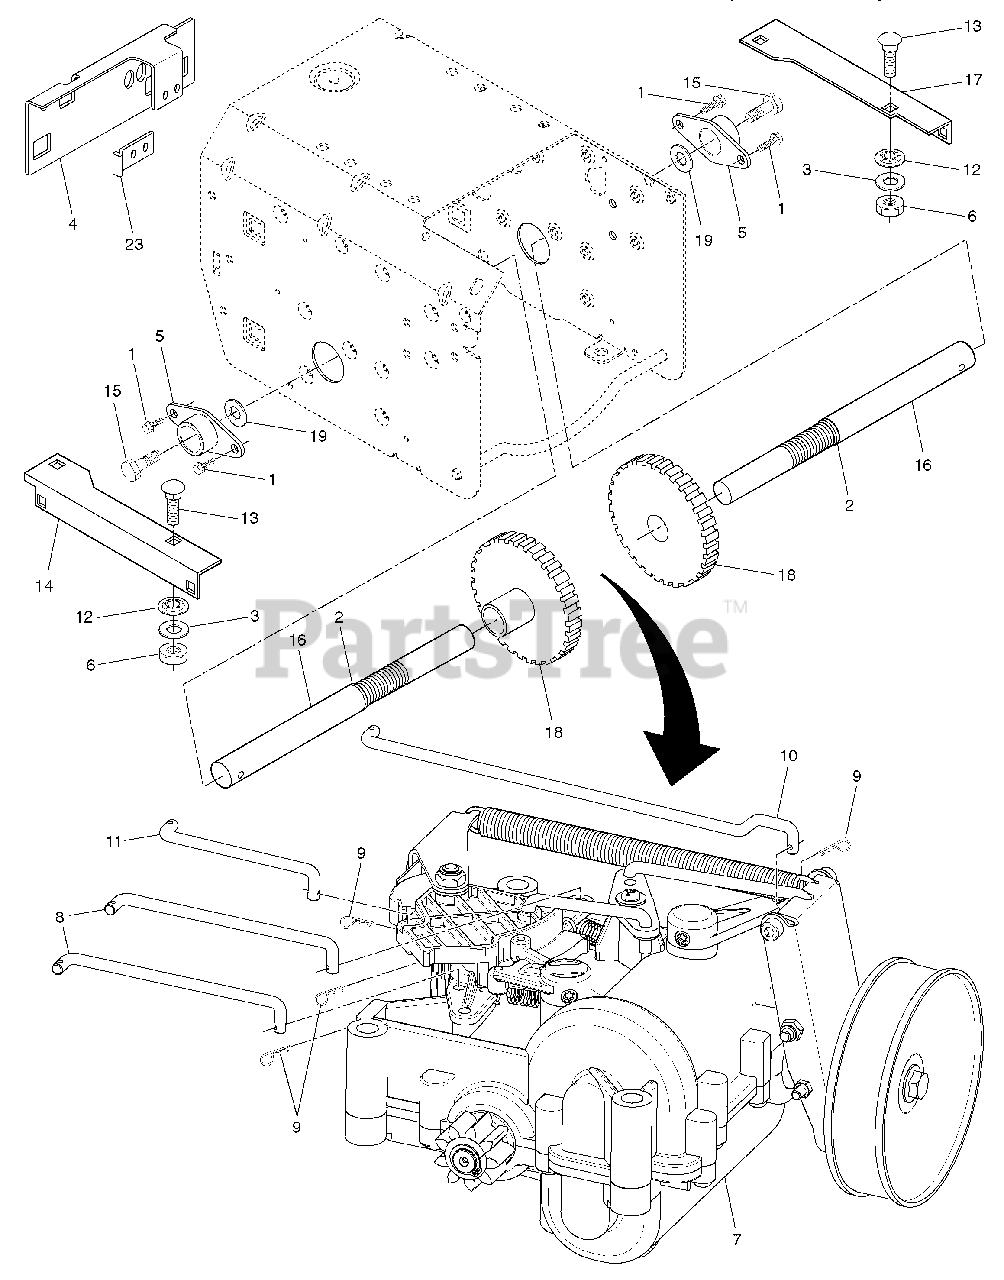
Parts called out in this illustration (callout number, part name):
1	Screw, Hex Head 5/16-18 x 3/4
2	Ring, Retaining
3	Washer, Flat
4	Plate, Rod Alignment
5	Bearing, Axle
6	Nut, Hex, Centerlock 3/8-16
7	Transmission Assembly
8	Control Rod, Steering
9	Retainer Clip
10	Control Rod, Clutch
11	Control Rod, Speed
13	Bolt, Carriage 3/8-16 x 3-1/4
14	Bracket, GT Transmission, RH
15	Screw, Hex Head
16	Shaft, Axle
17	Bracket, GT Transmission, LH
18	Gear, Axle
19	Washer, Flat
23	Spring, Leaf
